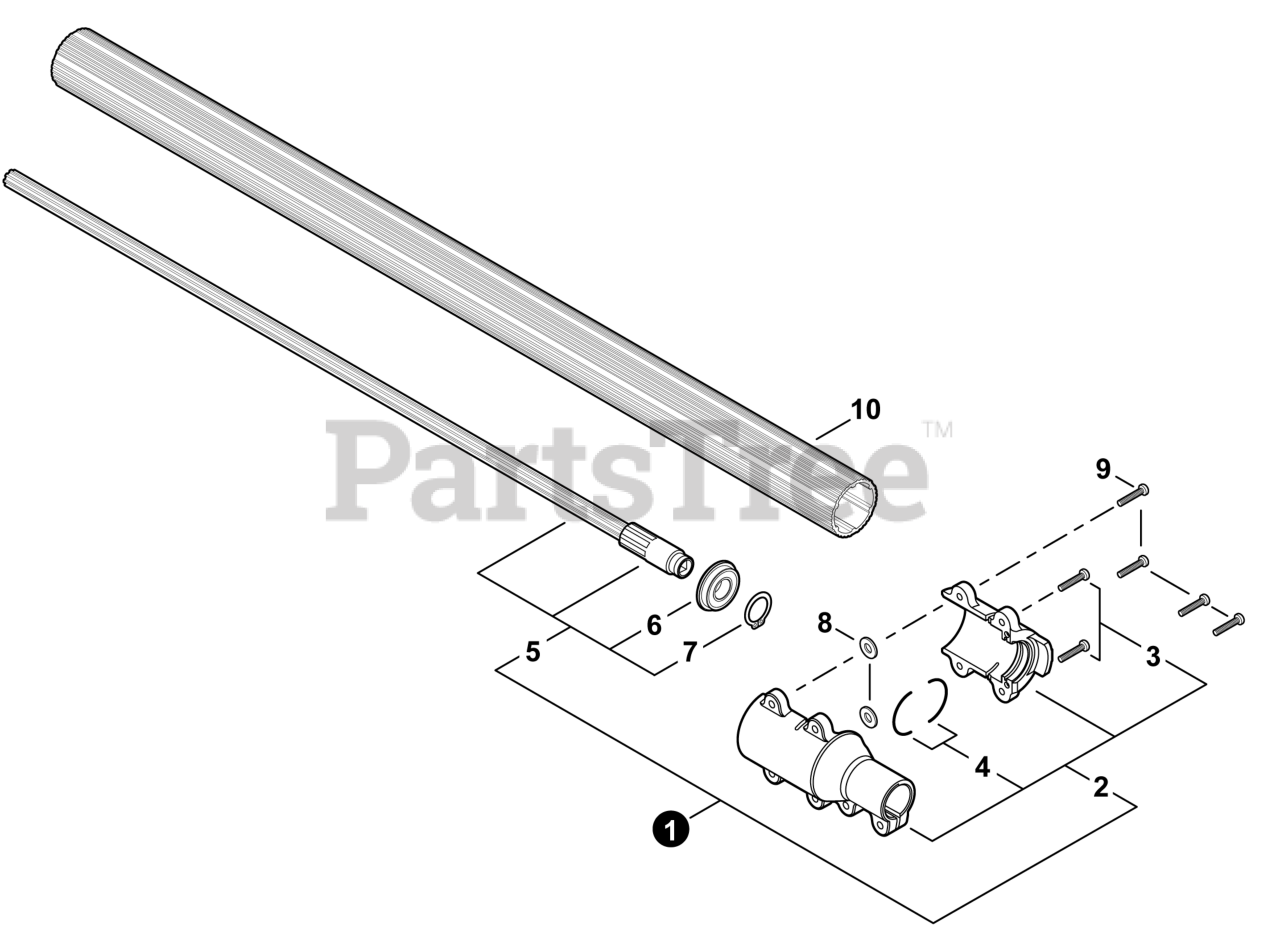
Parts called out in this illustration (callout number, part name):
1	COUPLING/DRIVESHAFT KIT
2	COUPLING ASSY, LOWER
3	BOLT, TORX 5x20
4	CUSHION
5	DRIVESHAFT ASSY, LOWER
6	BEARING, BALL 15x32x9
7	RING, RETAINING
8	WASHER 5
9	BOLT, TORX 5x20
10	PIPE, MAIN - ORANGE
